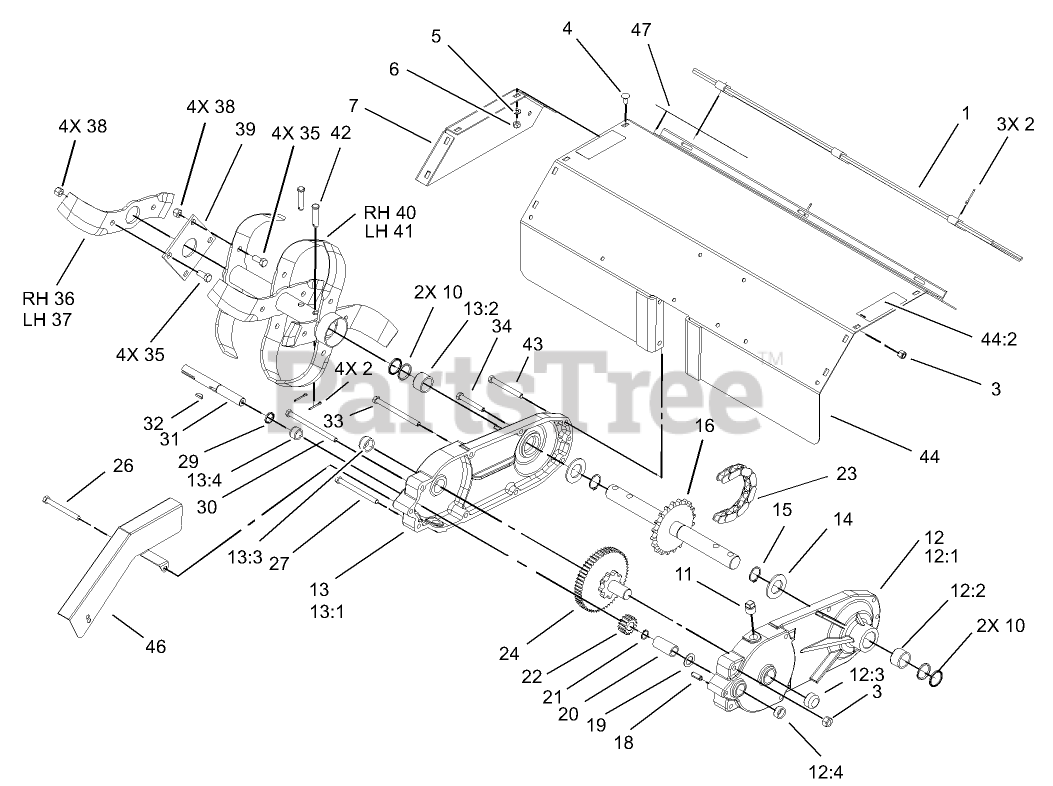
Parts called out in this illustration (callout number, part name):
1	GUARD ASM
2	PIN-COTTER
3	NUT-LOCK, NI
4	BOLT-CARR
5	WASHER-PLAIN
6	NUT-LOCK, NI
7	COVER-TINE END
11	PLUG-PIPE, SQH
12	Loose Parts Package
12:1	GEARCASE-TILLER
12:2	BEARING-NEEDLE
12:3	BEARING-NEEDLE
12:4	BEARING-NEEDLE
13	Loose Parts Package
13:1	GEARCASE-TILLER
13:2	BEARING-NEEDLE
13:3	BEARING-NEEDLE
13:4	BEARING-NEEDLE
14	WASHER
15	RING-RETAINING
16	TINE SHAFT ASM
18	PIN-ROLL
19	WASHER-THRUST
20	TUBE-SPACER
21	RING-SNAP
23	CHAIN
26	SCREW-HH
27	SCREW-HH
29	SEAL-OIL
30	SCREW-HH
31	SHAFT-INPUT
32	KEY-WOODRUFF
34	SCREW-HH
35	SCREW-HH
38	NUT-LOCK, NI
39	PLATE-TINE MOUNTING
40	RH TINE ASM
41	LH TINE ASM
42	PIN-CLEVIS
43	SCREW-HH
44	TINE SHIELD/DECAL ASM
44:2	DECAL-DANGER
46	GUARD-TILLER
47	DECAL-WORKHORSE
